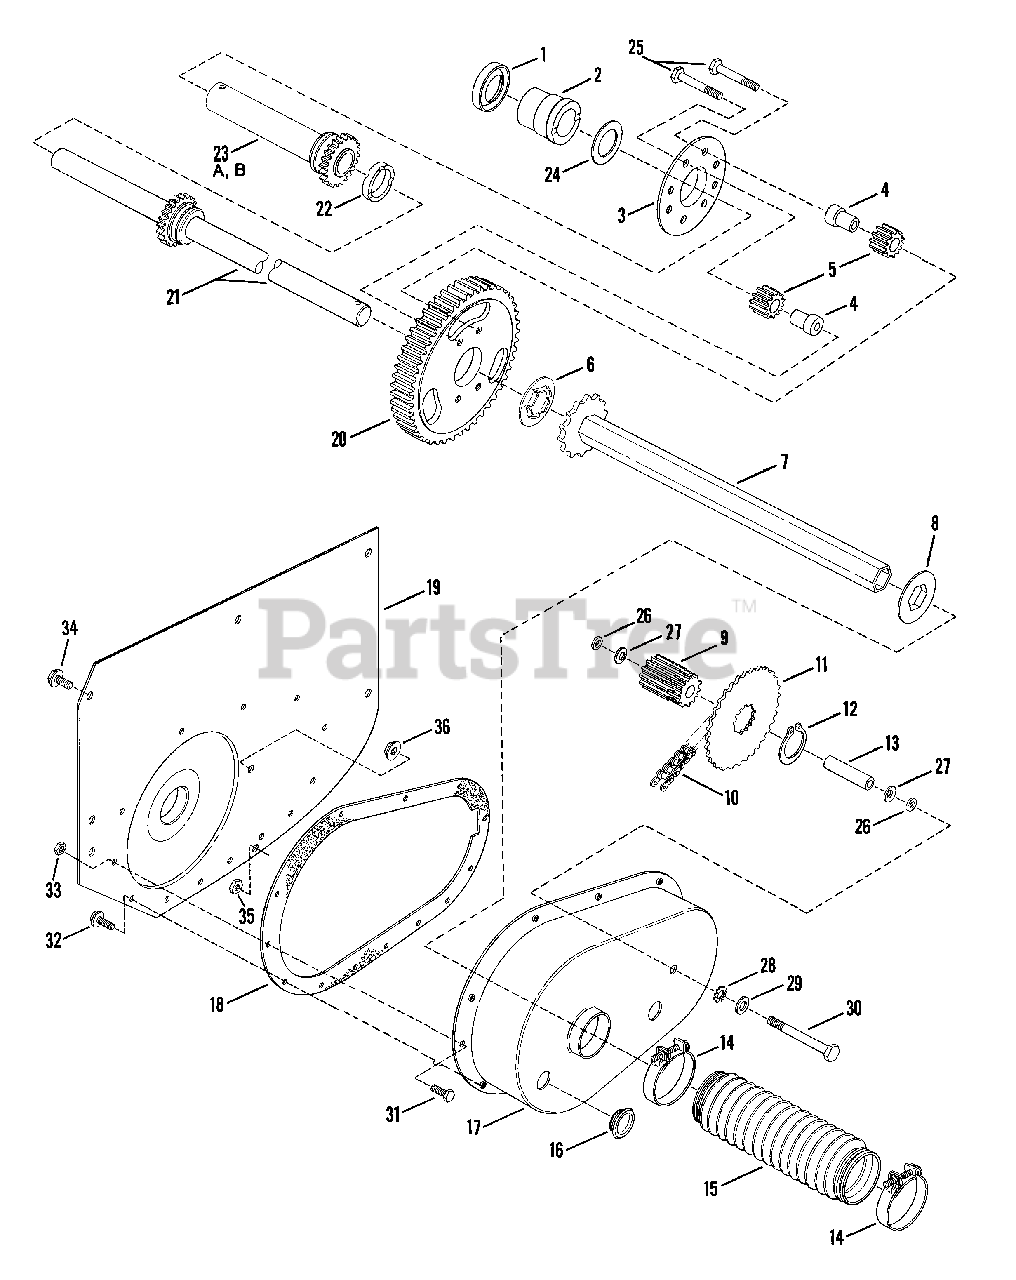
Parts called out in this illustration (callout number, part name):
1	SEAL, Oil
2	BEARING, Axle Right Hand Fender
3	PLATE, Differential
4	SPACER, Pinion
5	PINION GEARS, Differential
6	WASHER, Thrust
7	ASSEMBLY, Drive Hex Tube
8	WASHER, Hex
9	GEAR, 11 Teeth, 10 Pitch
10	CHAIN, 46 Pitch (#35)
11	SPROCKET
12	RING, External Retaining
13	SPACER
14	CLAMP, Boot
15	BOOT, Oil Seal
16	PLUG, Oil Fill & Check
17	CASE, Transmission
18	GASKET, Transmission Case
19	FENDER, Right Hand
20	GEAR, 63 Teeth, 10 Pitch
21	AXLE, Long
22	SPACER, Differential (1.25" ID x .425 Wide)
23A	AXLE, Short
23B	AXLE, Short (DX)
24	WASHER, Thrust
25	SCREW, 5/16-24 x 1-5/8" Special Lock Cap
26	O-RING, 5/16"
27	WASHER, 5/16" Belleville
28	WASHER, 5/16" External Tooth Lock
29	WASHER, 5/16" SAE Flat
30	BOLT, 5/16-24 x 2-5/8" (Idler)
31	SCREW, 1/4-20 x 5/8" Hex Head Cap, Grade 5
32	SCREW, 1/4-20 x 5/8" Self-Tapping
33	NUT, 1/4-20 Center Lock, Grade B or 5
34	SCREW, 5/16-18 x 5/8" Self-Tapping
35	NUT, 5/16-24 Hex
36	NUT, 5/16-24 Hex Flange Lock
